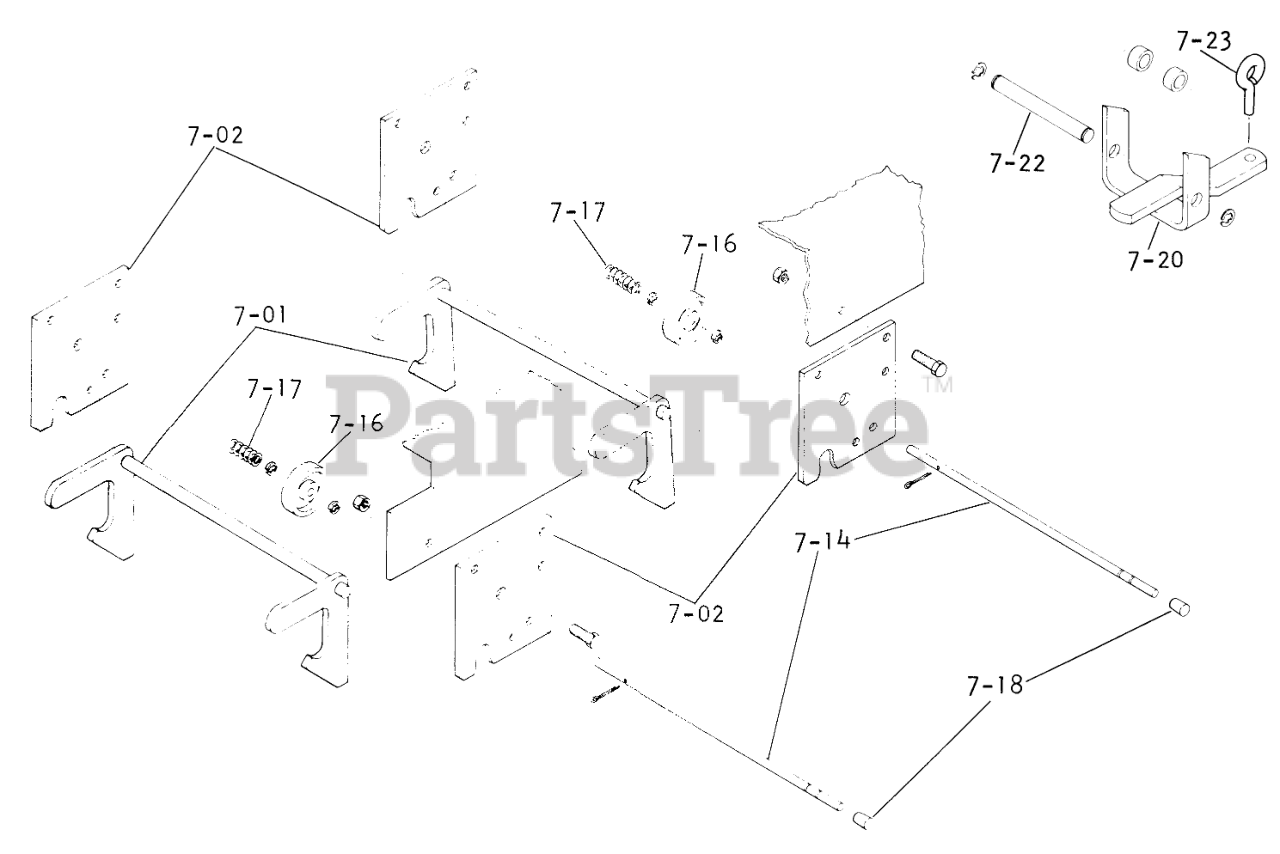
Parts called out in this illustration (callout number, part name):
7-01	Assy-Latch
7-02	Hitch Plate
7-14	Rod Lock
7-17	SPRING-COMPRESSION
7-18	Cap
7-20	Hitch
7-22	Pin
7-23	Pin-Tool
